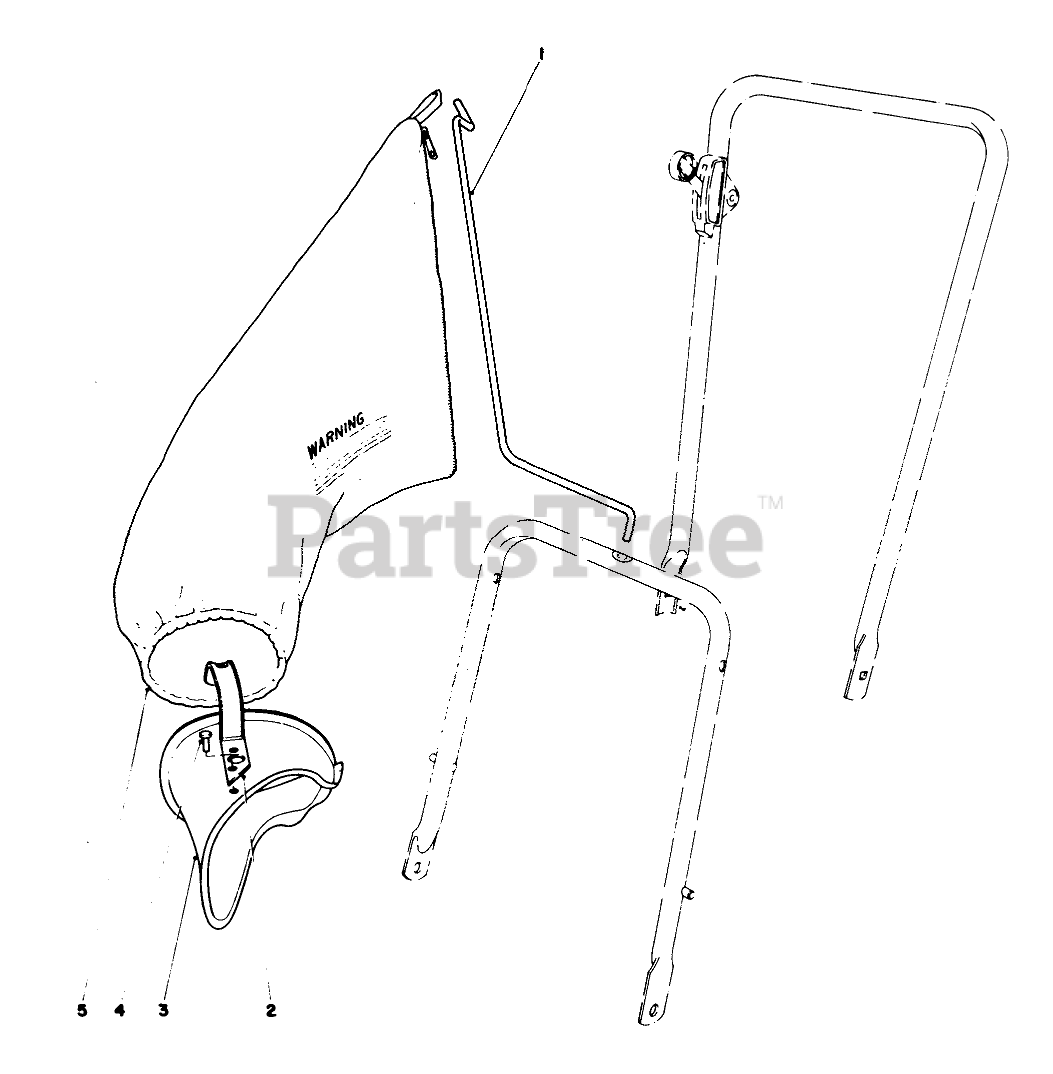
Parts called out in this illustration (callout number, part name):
1	BAG HANGER ROD
2	BAG CHUTE HANDLE
3	Grass Chute Assembly (Incl. Ref. #2 & 4)
4	RIVET 3/16 X 7/16
5	Grass Bag Assembly
